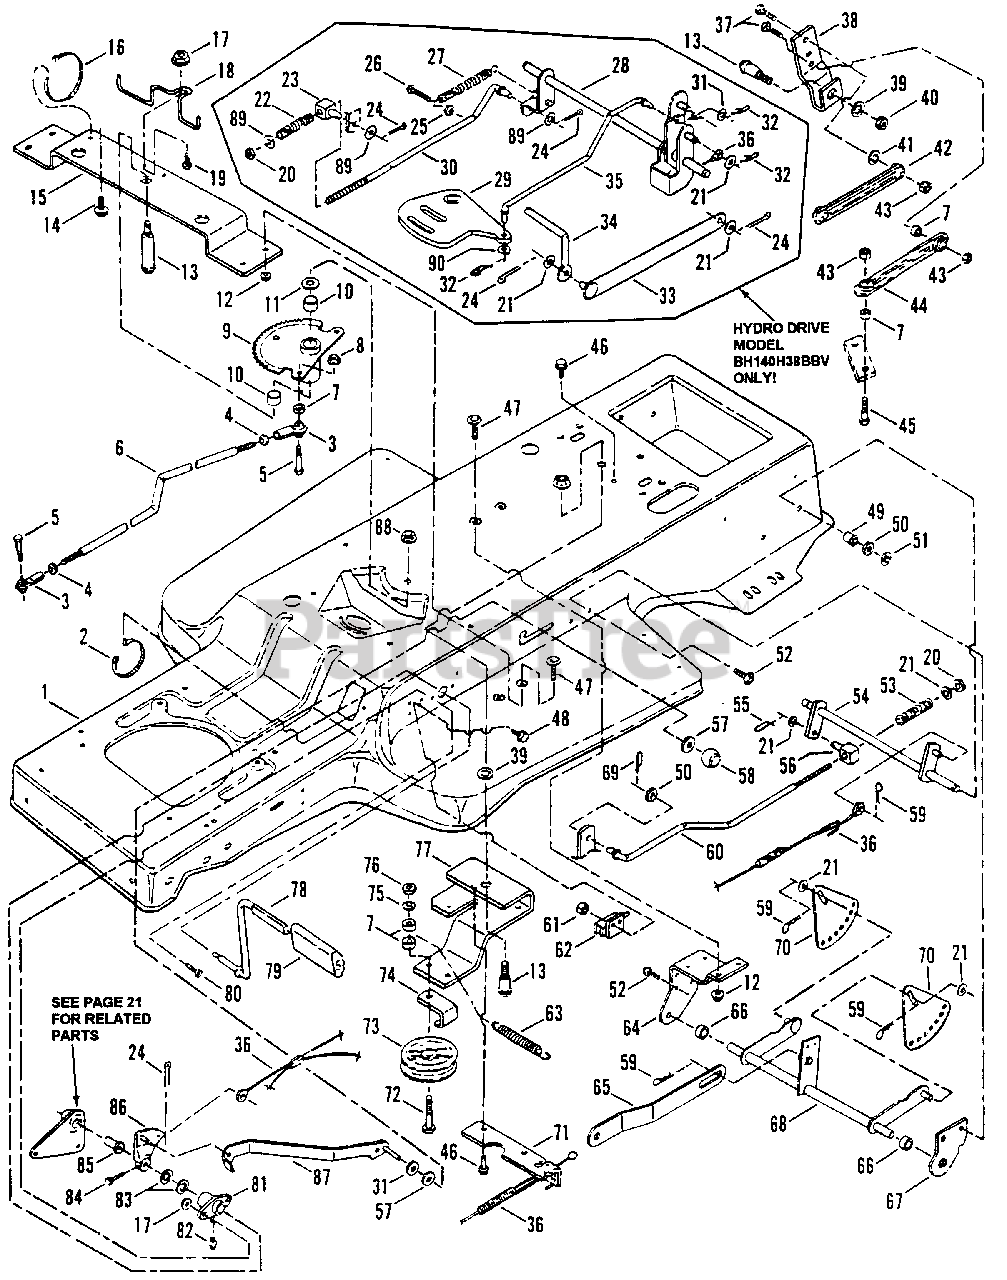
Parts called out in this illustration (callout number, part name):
1	FRAME, Tractor
2	TIE, Wire
3	BALL JOINT, 3/8-24
4	NUT, 3/8-24 Hex Jam
5	SCREW, 3/8-24 x 1 1/4" Hex Head Cap
6	LINK, Drag
7	SPACER
8	NUT, 3/8-16 Hex Flange Lock
9	ASSEMBLY, Sector Gear
10	BEARING, Sector Gear
11	WASHER, 3/4 Thrust
12	NUT, 1/4-20 Hex Flange Lock
13	BOLT, 1/2-13 x 2" Hex Flange Lock
14	SCREW, #10-24 x 1/2" Hex Washer Self-Tap (Torx)
15	BRACE, Sector Gear
16	TIE, Cable
17	NUT, 5/16 Hex Flange Lock
18	GUIDE, Drive Belt
19	BOLT, 5/16-18 x 3/4" Hex Flg. Lk.
20	NUT, 3/8-16 Hex Nyloc
21	WASHER, 3/8" Flat
22	SPRING, Brake
23	SWIVEL, In-line Brake
24	COTTER-PIN, 3/32 x 3/4"
25	NUT, 5/16-18 Hex Center Lock
26	SCREW, 5/16-18 x 1 1/4" Self Tapping
27	SPRING
28	WELDMENT, Brake Arm
29	ARM, Transmission Speed Control
30	ROD, Brake
31	WASHER, 5/16 Flat
32	COTTER-PIN, 3/8 Self-Lock'g.
33	LINK, Shift
34	ASSEMBLY, Shift Lever (Lower)
35	LINK, Speed
36	ASSEMBLY, Clutch/Brake Cable
37	SCREW, 3/8-16 x 1 1/4" Hex Head Cap
38	BELLCRANK, Shift Lever
39	WASHER, 1/2 Int. Tooth Lock
40	NUT, 1/2-13 Hex Flange Lock
41	WASHER, 3/8 Split Lock
42	LINK, Shift Lever
43	NUT, 3/8-16 Hex Center Lock
44	LINK, Shift Lever (Twisted)
45	SCREW, 3/8-16 x 1 1/2" Hex Head Cap
46	SCREW, 5/16-18 x 5/8" Self-Tapping
47	BOLT, 1/4-20 x 5/8" Carriage
48	SCREW, #10-32 x 5/8" Hex Washer Head
49	BEARING, Nylon
50	WASHER, 1/2 Flat
51	RING, Retaining
52	SCREW, 5/16-18 x 5/8" Truss Head (Torx)
53	SPRING, Brake
54	WELDMENT, Brake Pivot
55	COTTER-PIN, 1/16" x 1.42" Self-Locking
56	SWIVEL, Brake Link
57	WASHER, 5/16 Nylon
58	KNOB, Push/Pull
59	COTTER-PIN, 5/16 (Self-Locking)
60	ROD, Brake
61	NUT, #10-32 Hex Nyloc
62	SWITCH
63	SPRING
64	BRACKET, Rear Lift/PTO Lever
65	LINK, Lift
67	BRACKET, Deck Hang Pivot
68	WELDMENT, Rear Lift
69	COTTER-PIN, 1/16 x 1 127/64' (Self-Locking)
70	PLATE, Lift Sector
71	EXTENSION, Idler Arm
72	SCREW, 3/8-16 x 2 1/4" Hex Head Cap
73	PULLEY
74	GUIDE, Pulley
75	WASHER, 3/8 Split Lock
76	NUT, 3/8-16 Hex
77	ARM, Idler (Traction Drive)
78	PEDAL, Park Brake
79	PAD, Pedal
80	SCREW, 3/8-16 x 7/8" Truss Head (Torx)
81	ASSEMBLY, Foot Shaft Pivot
82	FITTING, Lube
83	WASHER, 5/8 Flat
84	PIN, 3/16 x 1 1/2" Clevis
85	BEARING, Flange
86	ASSEMBLY, Clutch Brake Arm
87	LATCH, Park Brake
88	NUT, 1/2-13 Hex Center Lock
89	WASHER, 3/8" Flat
90	WASHER, .06 x .34 I.D. x .69 O.D., Grade 5
